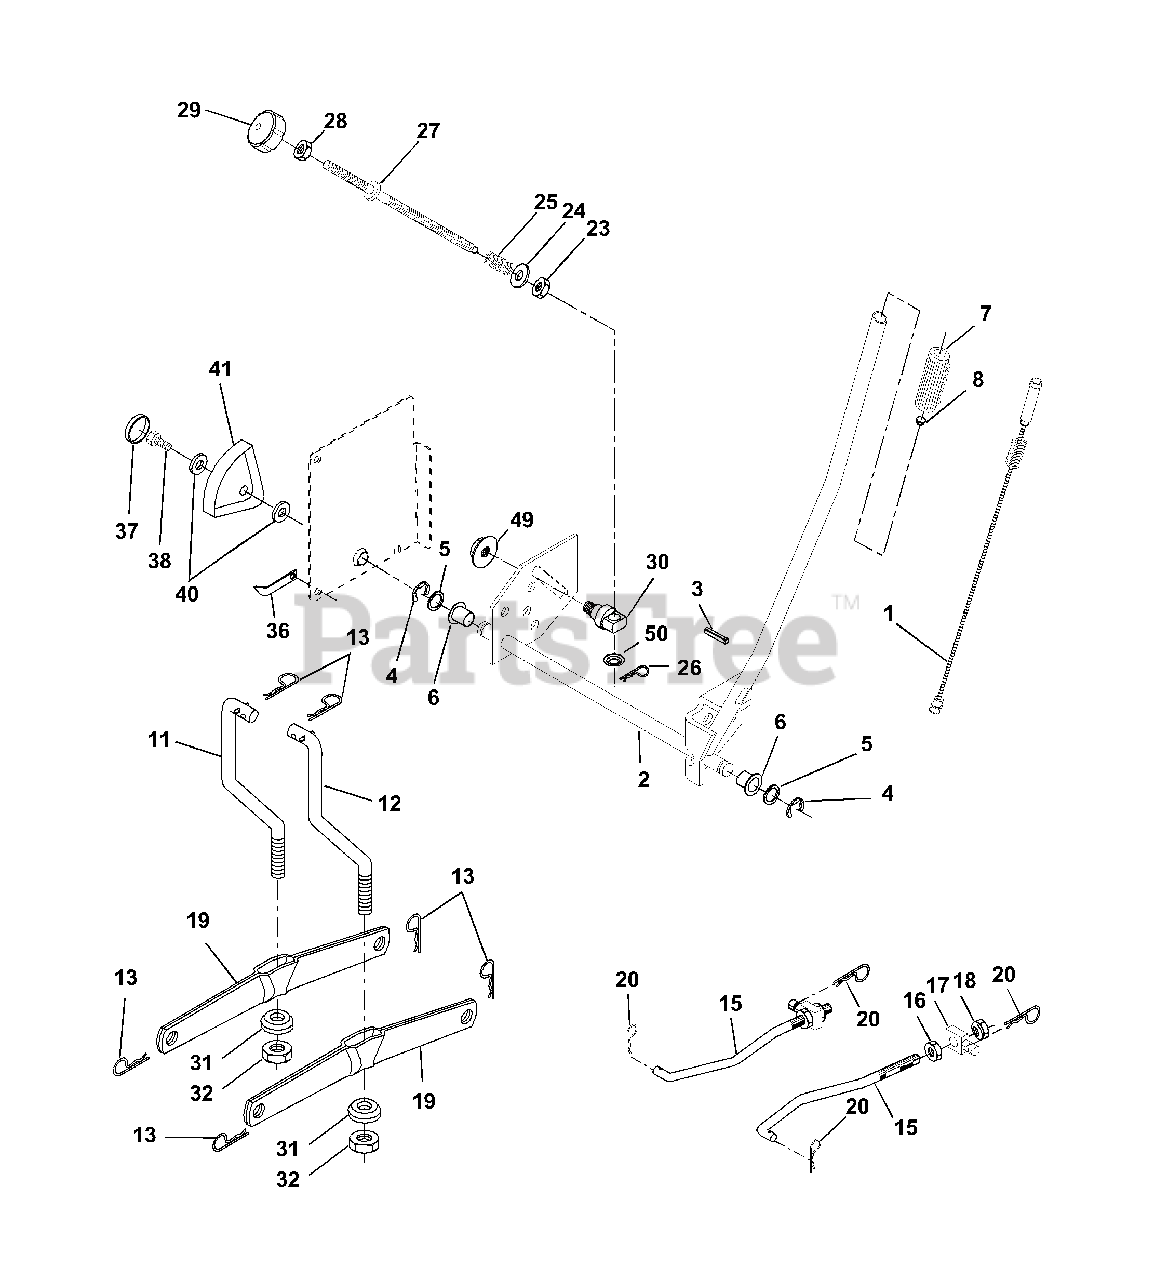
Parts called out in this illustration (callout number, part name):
1	Wire Asm Inner W/plunger
2	Shaft Asm Lift RH
3	Pin Groove 1 500 Zinc
4	E Ring #5133-62
5	Washer 21/32 X 1 X 21 Ga
6	Bearing Nylon Blk 629 Id
7	Grip Handle Bicycle Matte Blk
8	Button Plunger Black
11	Link Lift LH Fixed Length
12	Link Lift RH Fixed Length
13	Retainer Spring
15	Link Front
16	Nut Jam Hex 1/2-13 Unc
17	Trunnion Blk Zinc
18	Nut Lock W/Wsh 1/2-13 Unc
19	Arm Suspension Rear
20	Retainer Spring
23	Nut Special
24	Washer 13/32 X 5/8 X 16 Ga
25	Spring 2-1/8"
26	Retainer Clip
27	Rod Adj Lift Zinc 7.49 Wrk Lg
28	Nut Hex Jam 3/8-16 Unc
29	Knob Inf 3/8-16 Unc Blk W/sym
30	Trunnion Infin Height
31	Bearing Pvt Lift
32	Nut Crownlock 3/8 - 24
36	Pointer Height Indicator
37	Plug Hole Blk 1.485/1.515 Dia.
38	Screw 5/16-18 x 1
40	Washer 11/32 x 1-1/2 10 Ga.
41	Indicator Height
49	Nut Hex Flange Lock
50	Nut Push Phos & Oil
